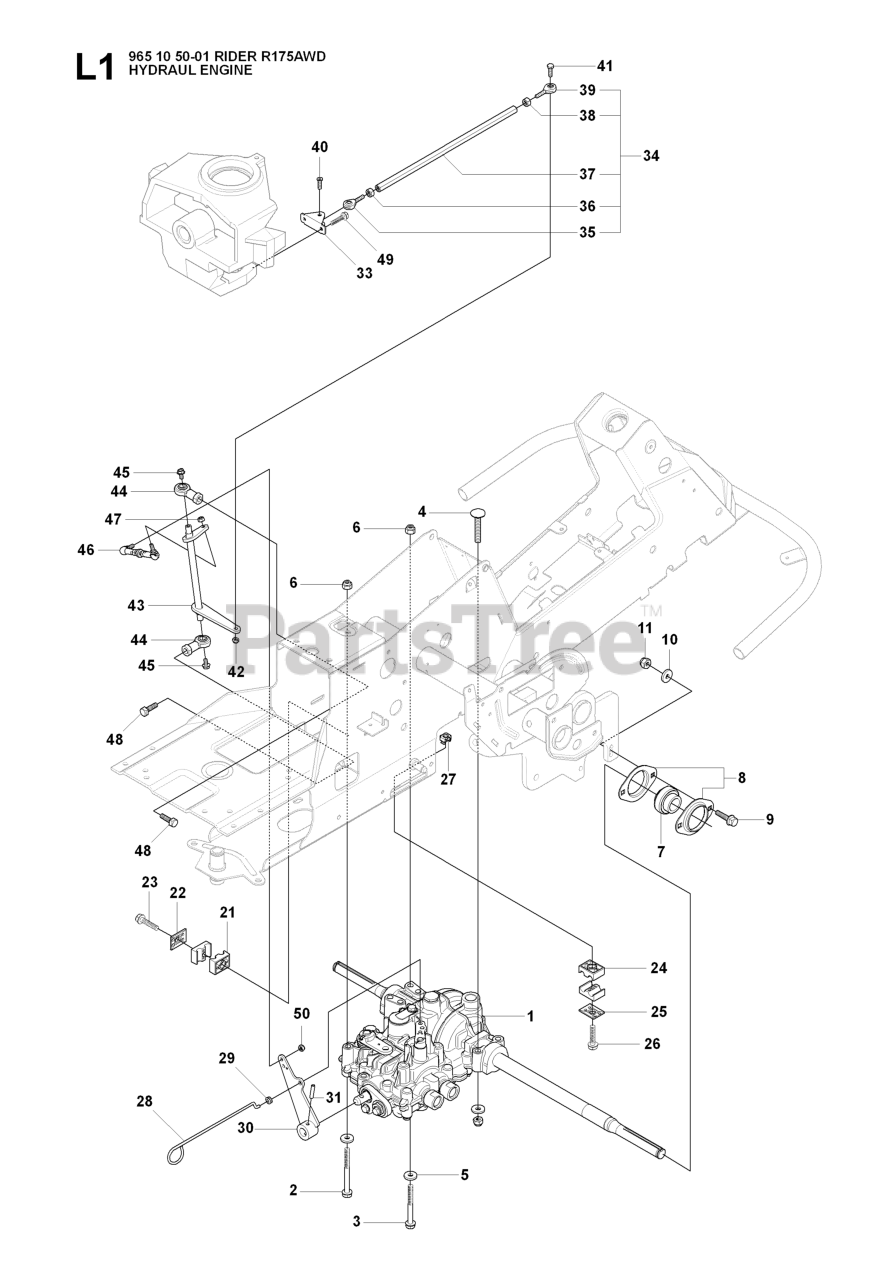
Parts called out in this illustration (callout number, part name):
1	%HYDRAULIC TRANSAXLE
5	WASHER BRB 8.4X17
6	LOCKNUT M8
7	BEARING
8	BEARING HOUSING
9	BOLT
10	WASHER BRB 8.4X17
11	LOCKNUT M8
21	PIPE CLAMP
24	PIPE CLAMP
25	COVER PLATE
26	SCREW EHHFM
29	FUEL TANK BUSHING
34	ROD
42	NUT FLANGE - M6
45	SCREW EHHFM
46	ADJUSTING ROD
47	NUT FLANGE - M6
48	Screw M10x25
50	LOCKNUT M6
